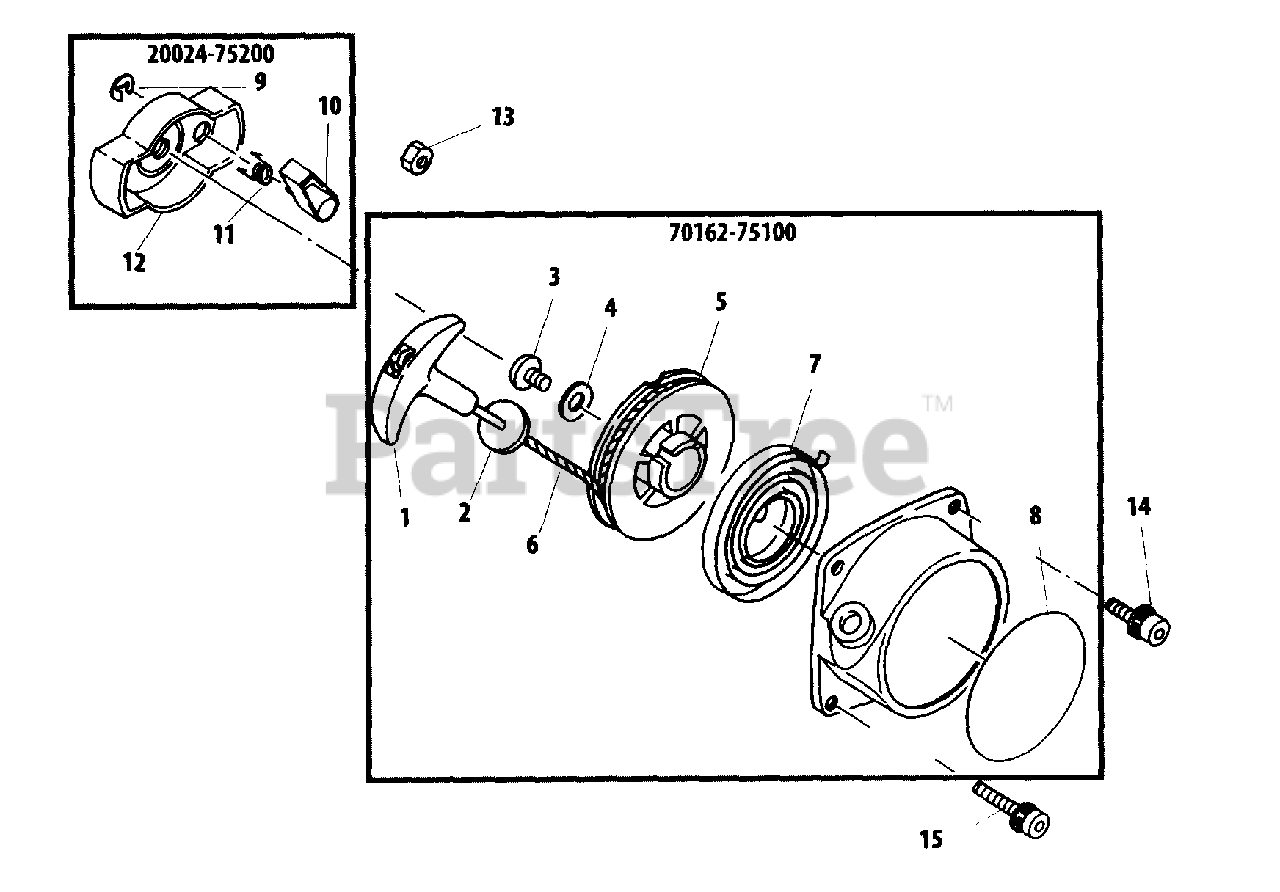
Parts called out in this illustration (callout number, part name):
1	GRIP, STARTER
2	GUIDE, ROPE
3	SCREW
4	WASHER
5	REEL, ROPE
6	ROPE
7	SPRING
8	LABEL
9	RING, RETAINING
10	PAWL, STARTER
11	SPRING, RETURN
12	CASE, PAWL
13	NUT
14	SCREW - 5X16
15	SCREW - 5X25
20024-75200	STARTER PAWL ASSY
70162-75100	STARTER ASSY
